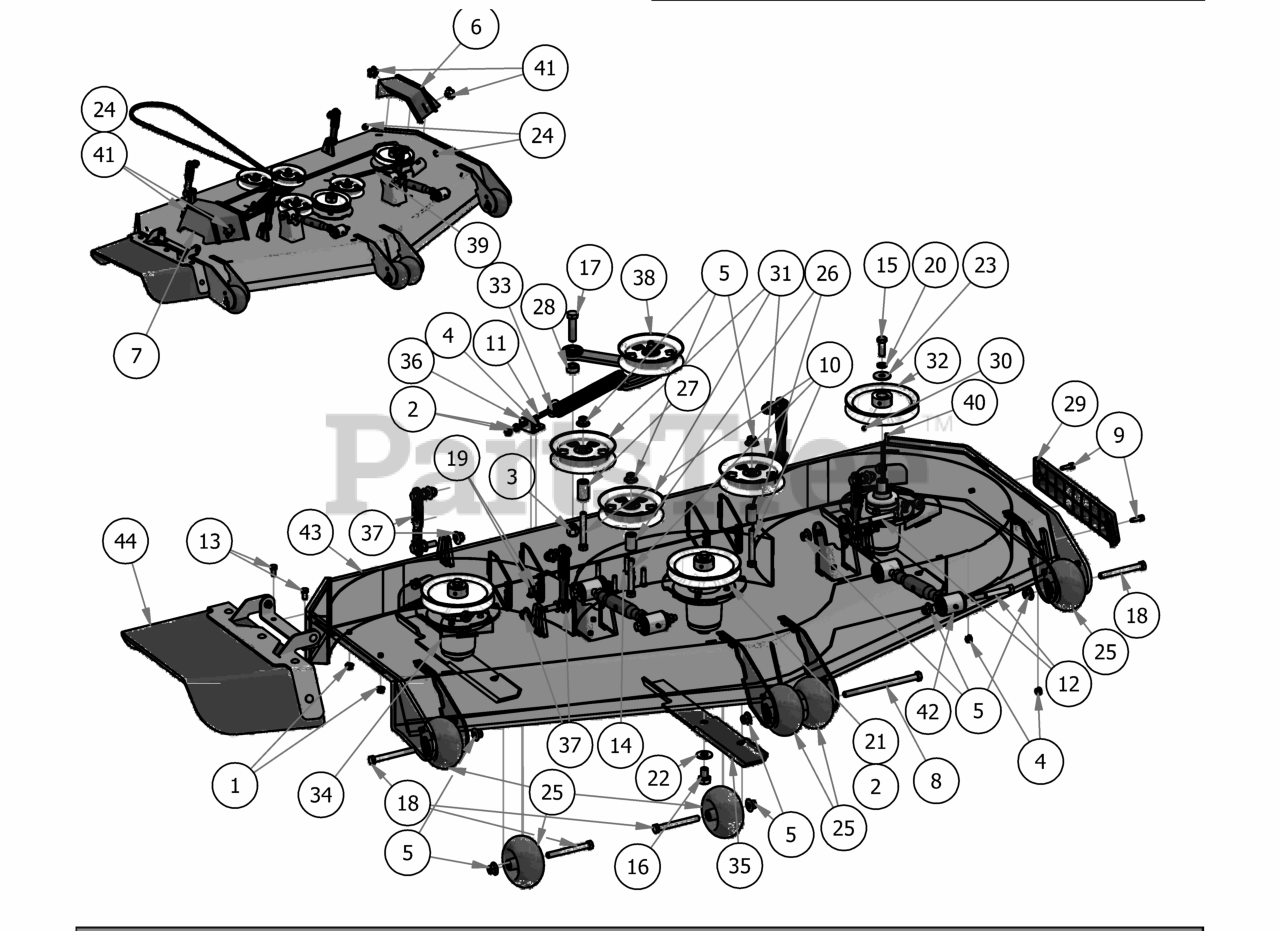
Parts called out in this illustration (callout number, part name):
1	3/8" Flange Nut
2	3/8" Hex Nut
3	5/8 Std NC Nylock Nut
4	5/16" Nylon Flange Nut
5	1/2-13 Nylon Flange Nut
6	2019 72" Left Outlaw Gen2 Pulley Cover
7	2019 72" Right Outlaw Gen2 Pulley Cover
8	1/2-13 x 8 Hex Bolt Grade 5
9	5/16-18 x 1 GR 5 Hex Bolt Zinc
10	1/2 x 3 1/2 Flange Bolt Grade 8
11	4" 3/8-16 Eye Bolt
12	1/2" x 4" Bolt (Grade 8)
13	3/8" x 3/4" Hex Bolt
14	3/8 x 1.5" Bolt
15	1/2"-20 x 1 1/2 - Grade 5 Fine Thread Bolt
16	5/8" x 1 1/2" Grade 8 Hex Bolt (Fine)
17	5/8" x 2 1/2" Grade 5 Hex Bolt (Coarse)
18	1/2" x 4 1/2" Bolt
19	5/16" x 7/8" Carriage Bolt
20	1/2" Lock Washer
21	3/8" Lock Washer
22	5/8'' Flat Washer
23	1/2" Belleville Washer
24	.360 ID Plastic Washer-Black
25	2019 Deck Wheel
26	.502 ID X .750 OD X 1.500 Long Spacer
27	1 3/4" Pulley Spacer
28	5/8" x 1/" Collar W/One Set Screw
29	REVISED TRIM BUMPER_20180226
30	5/16 Set Screw
31	5-3/4 Idler Pulley
32	7" Deck Pulley
33	2019 Outlaw Gen2 Deck Spring
34	OUTLAW SPINDLE ASSEMBLY
35	72" High Lift Fusion Blade
36	2019 Deck Eye Bolt Tab
37	Deck Hangar Assembly
38	2019 Rebel Rogue Deck Idler
39	B202 Belt for 72" Outlaw
40	1/4" x 1" Key
41	5/16" Knob
42	Turnbuckle
43	2019 Sloped 72" Deck
44	2019 Outlaw Gen2 Chute Assembly
